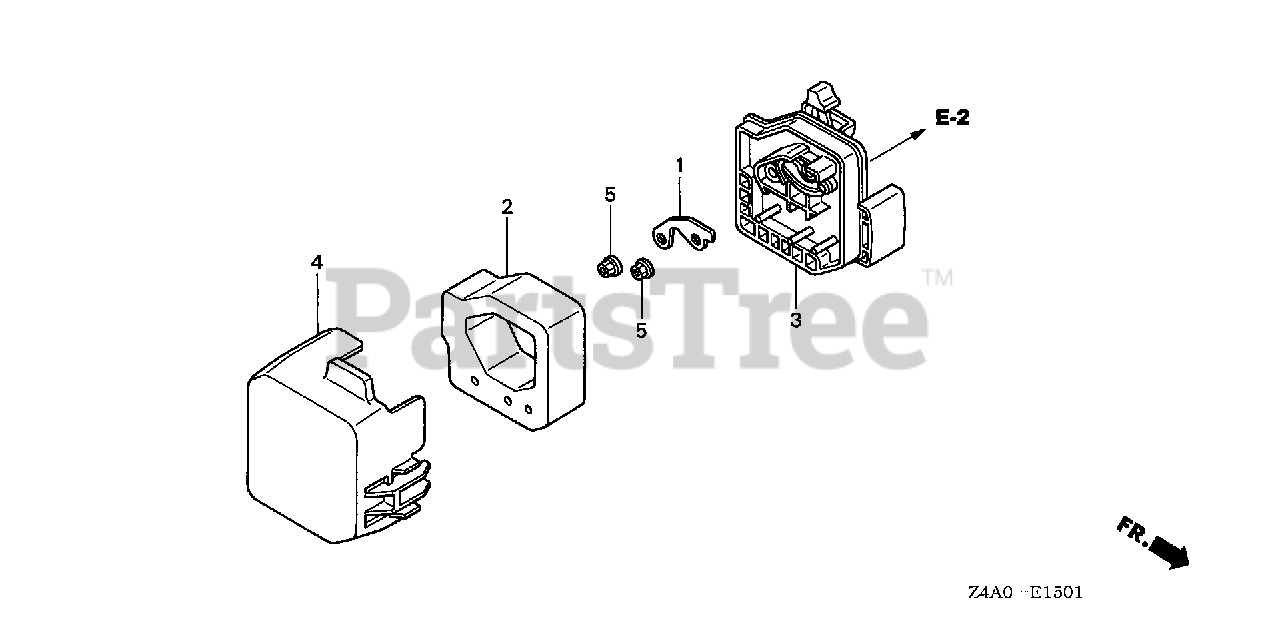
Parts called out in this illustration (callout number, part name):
1	PLATE, OIL TRAP
2	ELEMENT, AIR CLEANER
3	HOUSING, AIR CLEANER
4	COVER, AIR CLEANER
5	NUT, FLANGE (5MM)
